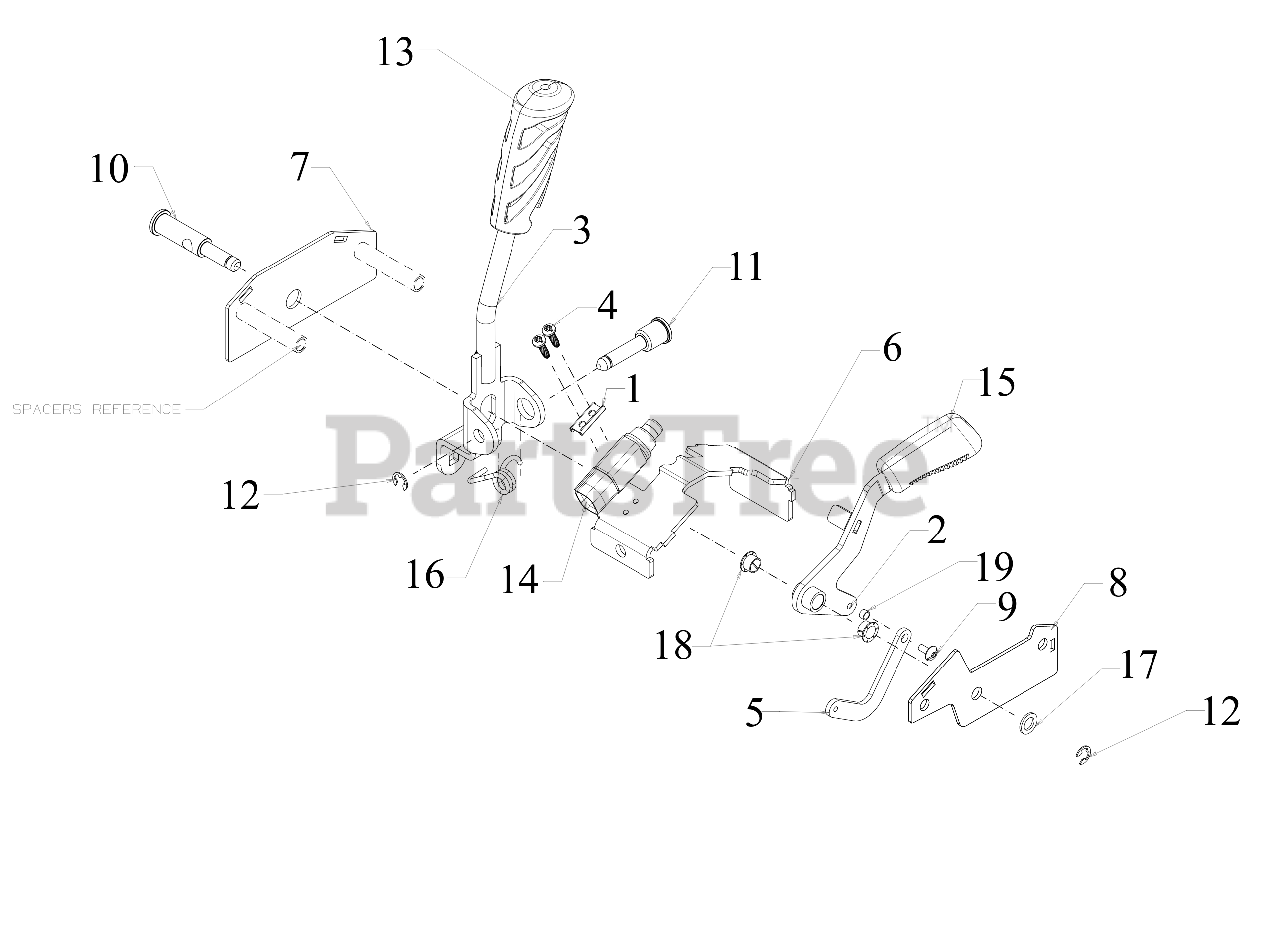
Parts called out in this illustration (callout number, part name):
1	PLATE-SWITCH
2	DIFFERENTIAL HANDLE ASSEMBLY
5	ASSEMBLY
6	ASSEMBLY
7	ASSEMBLY
8	ASSEMBLY
9	SCREW-#10-24 x .400 SELF TAP
12	EXTERNAL RETAINING RING 7MM
14	SEALED PLUNGER SWITCH
15	BRAKE HANDLE GRIP
16	TORSION SPRING
17	FLAT WASHER
18	FLANGE BEARING .375X.580X.250
